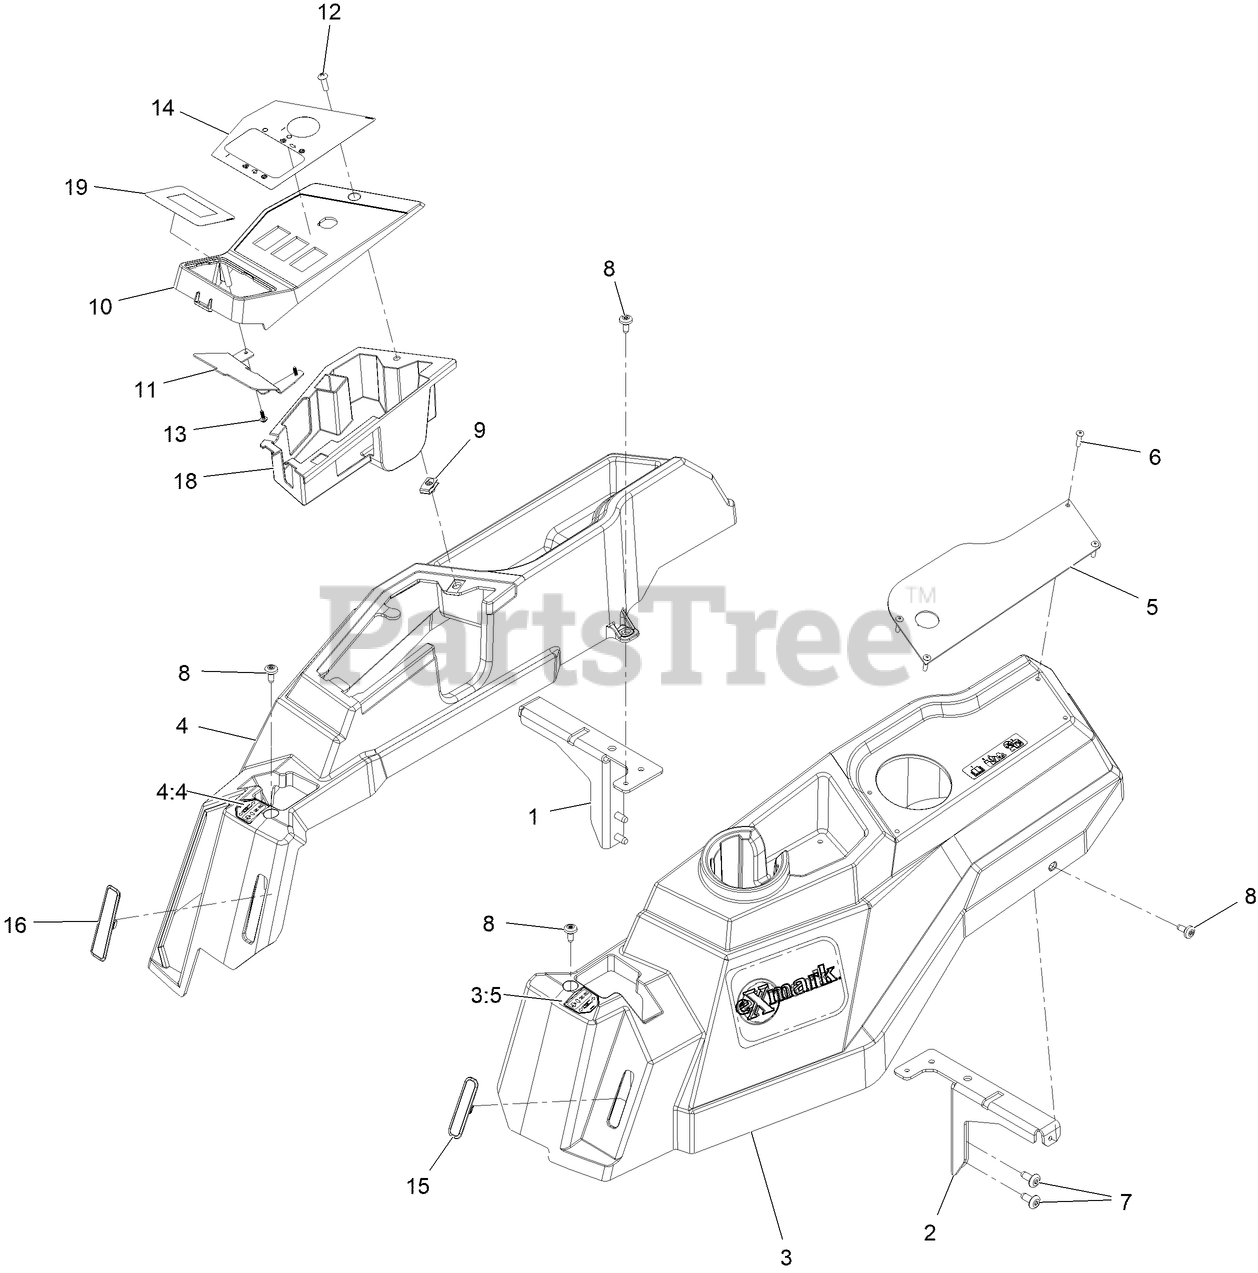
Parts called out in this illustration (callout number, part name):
1	SUPPORT-POD, RH
2	SUPPORT-POD, LH
3:5	DECAL - CONTROL LEVER, LH
4:4	DECAL - CONTROL LEVER, RH
5	PLATE-COVER, POD
6	RIVET-TRIFOLD
8	SCREW-SHOULDER
10	POD-CONTROL
11	COVER-CONSOLE
12	SCREW-PRH
13	SCREW-PLASTIC,TBFH
14	DECAL-CONTROL PANEL
15	PLUG-POD LH
16	PLUG-SC
18	COVER-SWITCH
19	DECAL-MESSAGE DISPLAY
